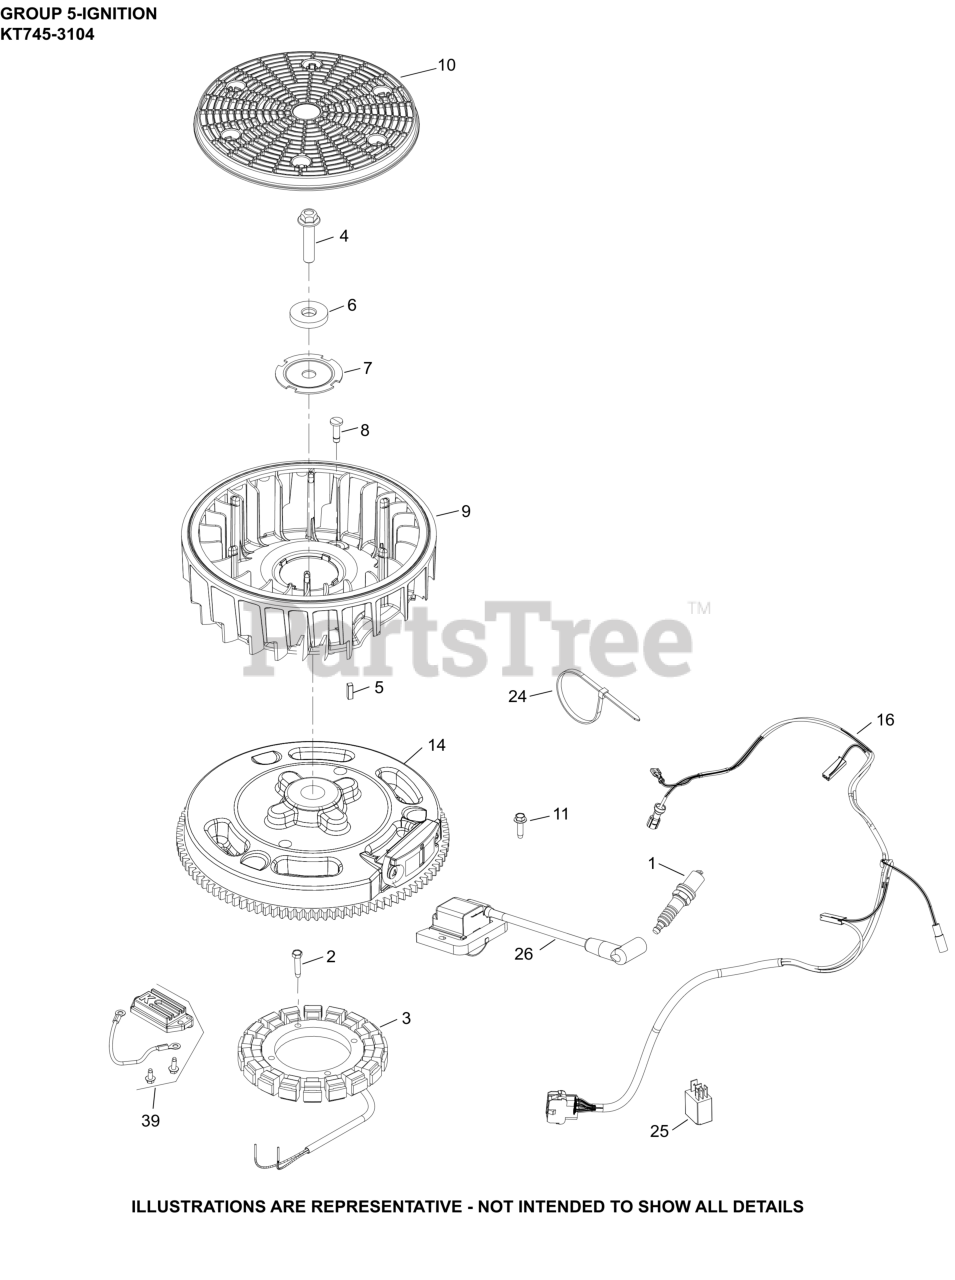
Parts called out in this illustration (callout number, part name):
1	SPARK PLUG, RFI
2	SCREW, THREAD FORMING
3	KIT, 15 / 20 AMP STATOR
4	SCREW, HEX FLANGE
5	KEY, SQUARE
6	WASHER, FLAT
7	PLATE, FAN MOUNTING
8	RETAINER, FLYWHEEL FAN
10	SCREEN, GRASS
11	SCREW, THD FRM-USE 25 086 473-S
14	FLYWHEEL ASSEMBLY
16	HARNESS, WIRING ASSEM.W/FUEL SHUT DOWN
26	MODULE, MAGNETO DIGITAL IGNITION
39	KIT, REGULATOR RECTIFIER
